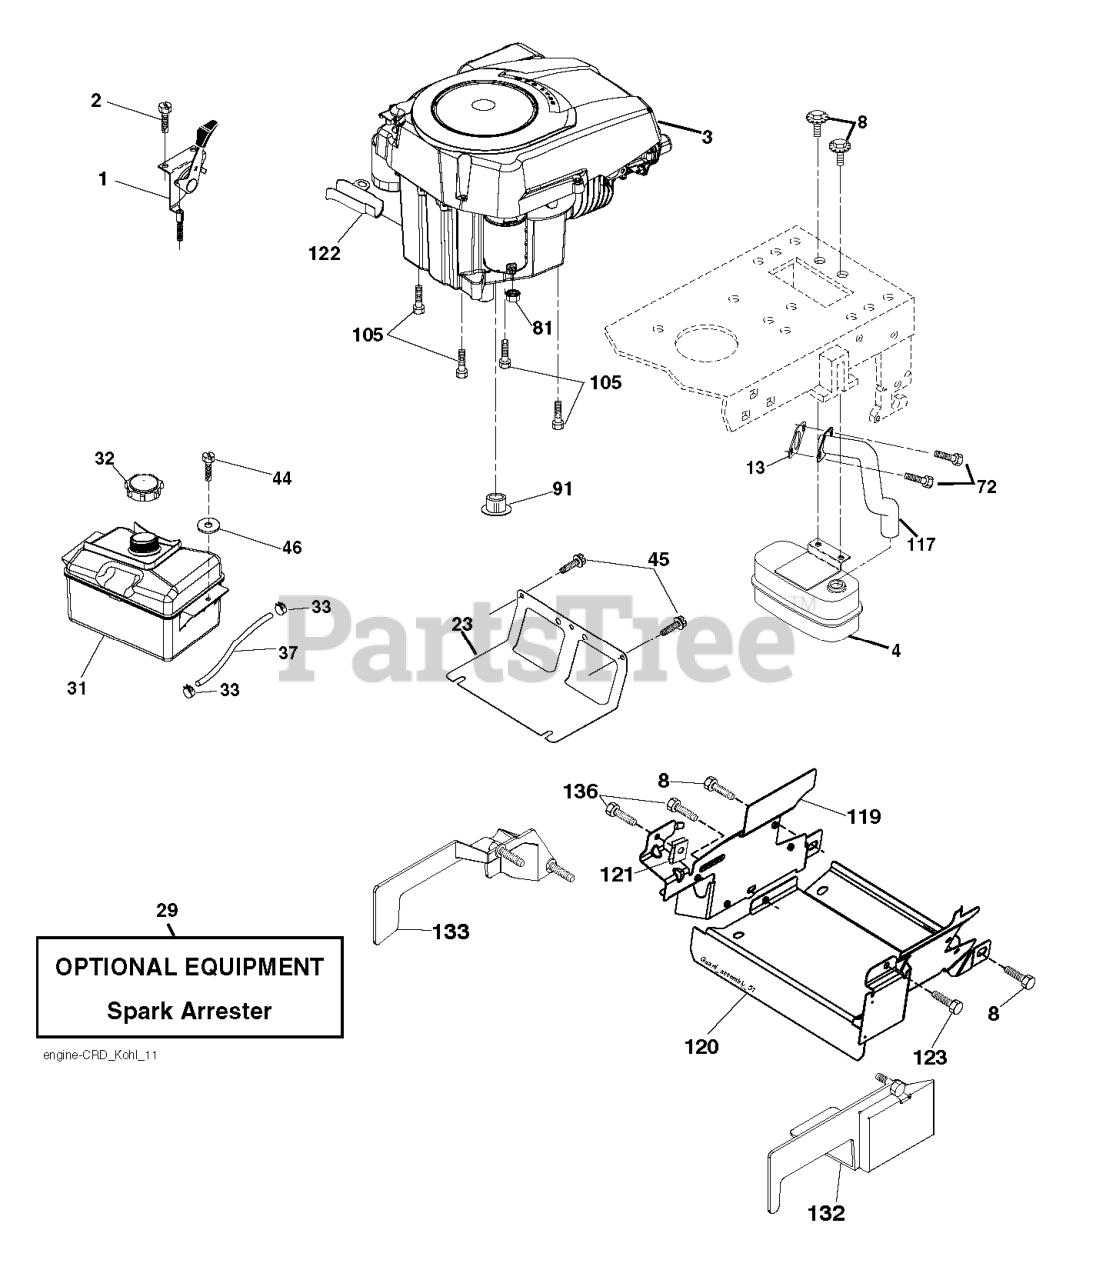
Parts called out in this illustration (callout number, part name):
1	CONTROL.TH/CK.C.
2	SCREW.#10 X 0.750.BOS
4	MUFFLER.SINGLE.CYL.KOHL/B&S
8	BOLT.5/16-18UNCX3/4 W/SEMS.BLK
13	GASKET.EXHAUST.KOHLER
23	SHIELD.BROWNING.DBR.GUARD
29	KIT.SPARK ARRESTOR 794945 B&S
31	RP TANK FUEL FRT 1.5 GAL
32	CAP ASM.FUEL.2.25"FR.
33	HOSE CLAMP
37	LINE.FUEL.20
44	SCREW HEXWSHR 1/4-20X3/4
45	SCREW, 3/8-16X3/4
72	SCREW.SOCKET HD.5/16-1
81	NUT
91	BUSHING.1.375OD
105	SCREW 3/8-16X1
117	RP.TUBE.EXHAUST.KOHL.COURAGE
119	LENKRAD
120	GUARD 532199767
122	EXTENSION DRAIN OIL
123	SCREW, 5/16-18 X 1/2
132	SHIELD RIGHT
133	SHIELD LEFT
136	SCREW.1/4-20X5/8
